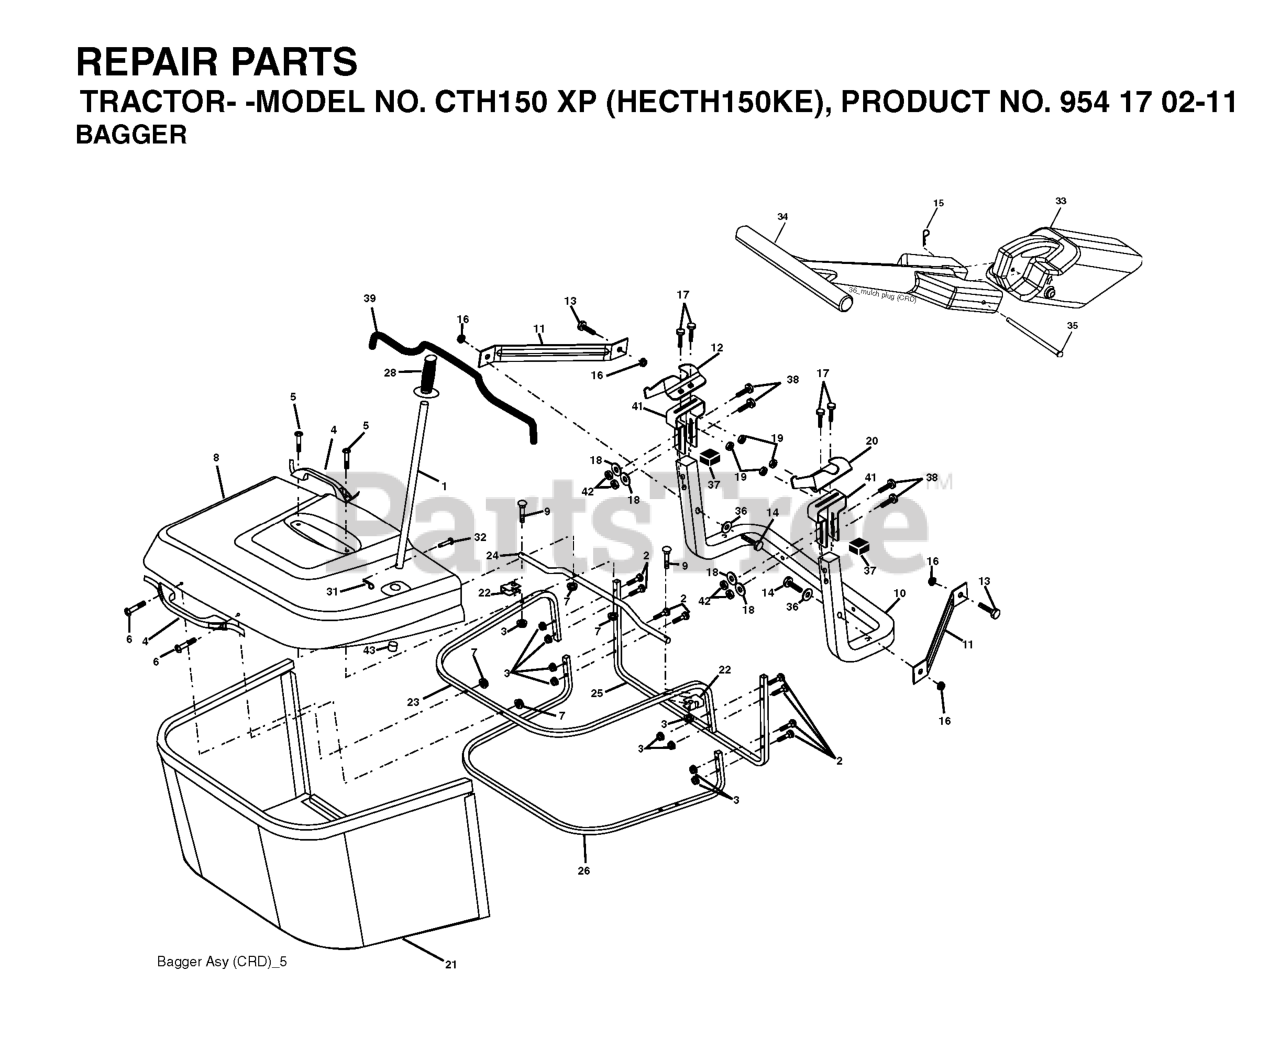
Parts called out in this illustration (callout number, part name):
1	TUBE HANDLE
2	Bolt Carriage 1/4-20 x 2.0 Gr.5
3	NUT T
4	HANDLE.BAGGER.W/LVRS.BLK.CRD
5	SCREW.PAN.HEAD
6	REPL BY 532 75 00-29
8	COVER.PNT.BGR.CRD.WSLOTS.MS668
9	Bolt Carriage 1/4-20 x 2.25d x Gr.5
10	TUBE
11	BRACKET.SUPPORT.UPPER.BAG.CRD
13	BOLT
14	BOLT-HEX EAK
15	RETAINER-SPRNG RB
16	NUT LOCK FLG 3/8-16 UNC
17	RP BOLT 5/16-18 X3/4 ZN/YEL GR
18	WASHER M
19	NUT LOCK HEX FLANGE 5/16-18
20	BRACKET
21	GRASS BAG
22	BRKT.SIDE.BAG.CRD
23	TUBE.UPPER.BAG.CRD
24	TUBE.PIVOT.BAG.CRD.BLACK
26	TUBE.LOWER.BAG.CRD
28	GRIP.HANDLE.BLACK
31	RETAINER CLIP
32	RIVET,DRILLED
33	MULCH PLUG, CTH150
34	HANDLE.MULCHER.92.CRD (2 2)
36	WASHER
37	Plug Support Bagger CRD
38	BOLT.5/16-18X2.5
39	SEAL.TRIM.37'
41	BRKT.VERT.ADJ.BAGGER.CRD
42	NUT.71038.31-18.HEX.NYLOCK
43	PLUG, TUBING END
